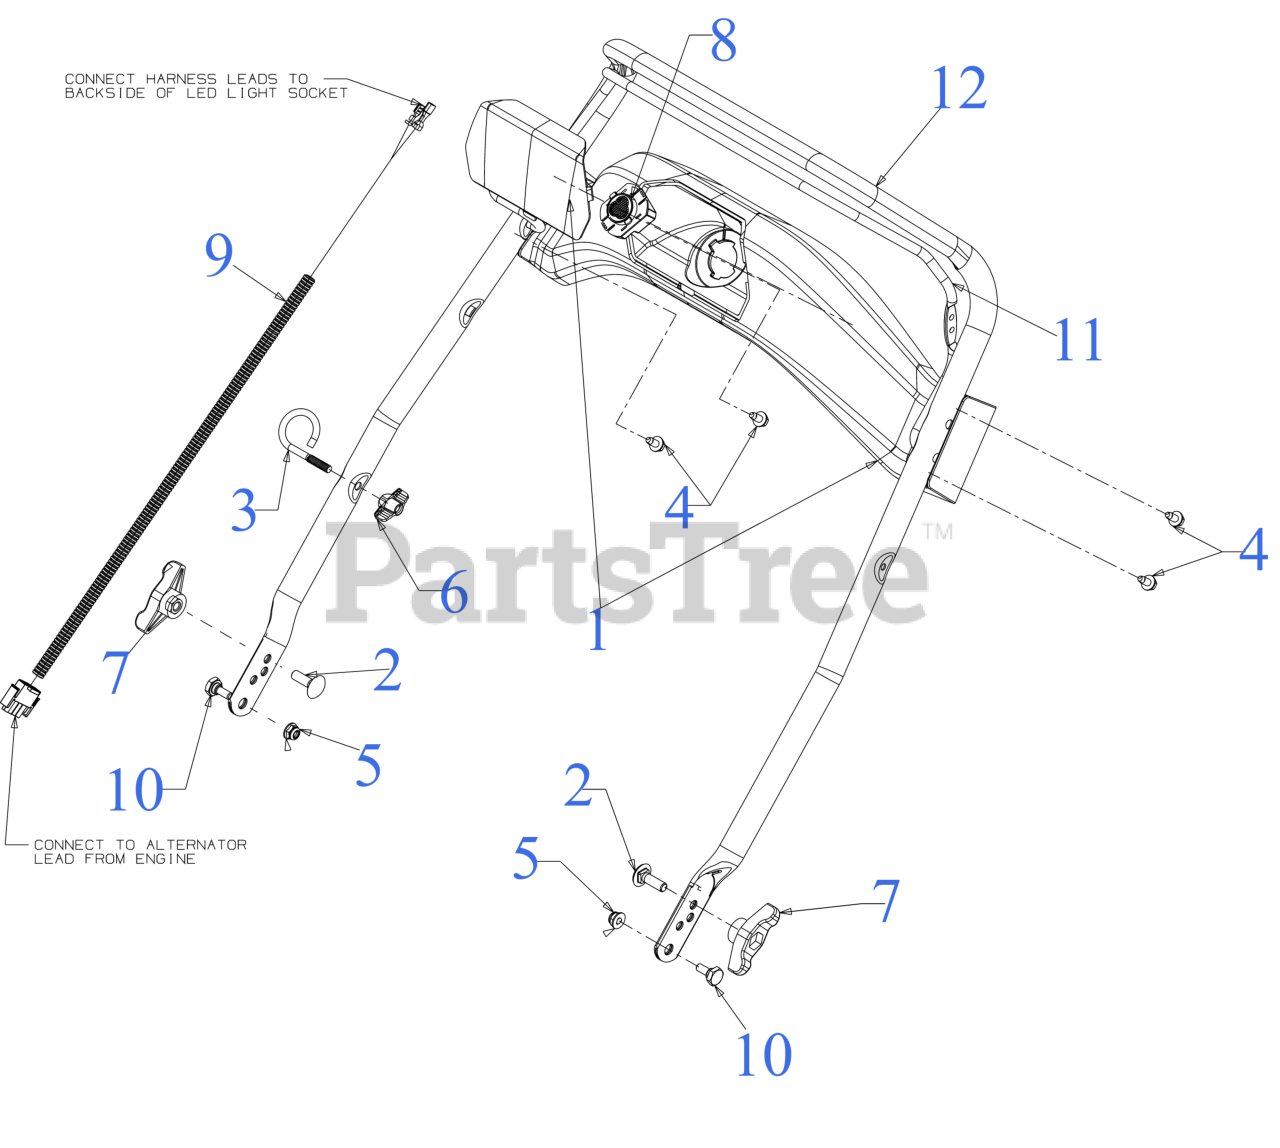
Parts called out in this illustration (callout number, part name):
1	HANDLE PANEL ASSEMBLY
2	SCREW 5/16-18 x 1.00 GR5
3	EYEBOLT 1/4-20
4	SCREW 1/4-20 X.500
5	FLANGE LOCK NUT
6	HANDLE KNOB
7	WING KNOB 5/16-18
8	LED HEADLIGHT & SOCKET (150 LUMNES)
9	HARNESS (SINGLE LIGHT)
10	SHOULDER SCREW
12	UPPER HANDLE
